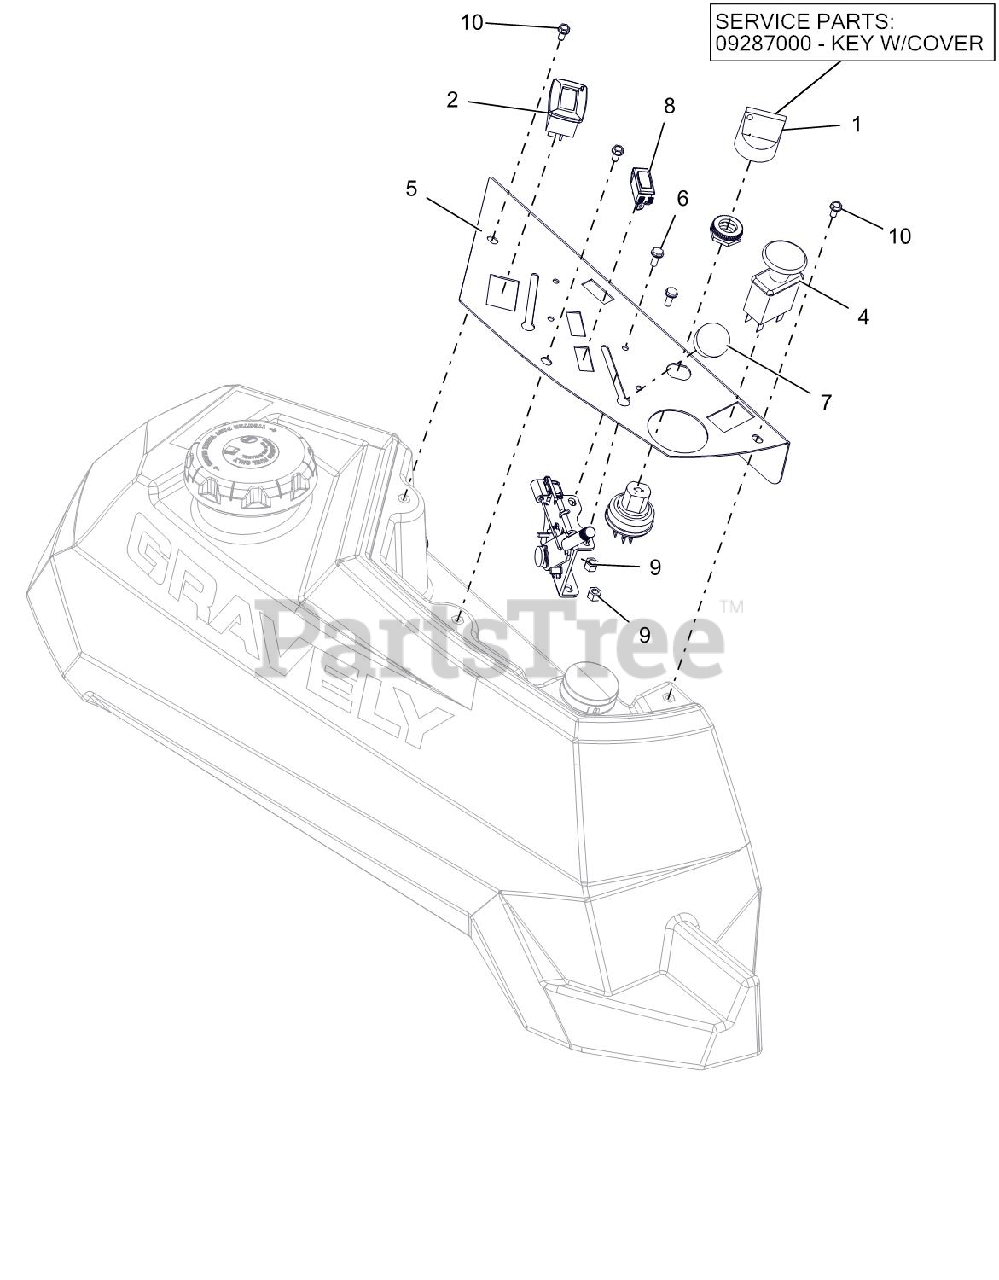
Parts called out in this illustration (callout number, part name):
1	KEY, W/ SHIELD
1	SWITCH, IGNITION
2	METER, HOUR W/MAINTENANCE
4	SWITCH, CLUTCH
5	PT100 CONTROL PANEL - RED
6	@SCR-MCH 10-24X.50 HWH YWZC
7	KNOB-CONTROL-BLACK .38-16X.50
8	LIGHT,INDICATOR
9	@NUT-LK-NYL 10-24 W/INSRT YWZC
10	SCR-MCH 10-24X.38 HWHSTAINLESS
